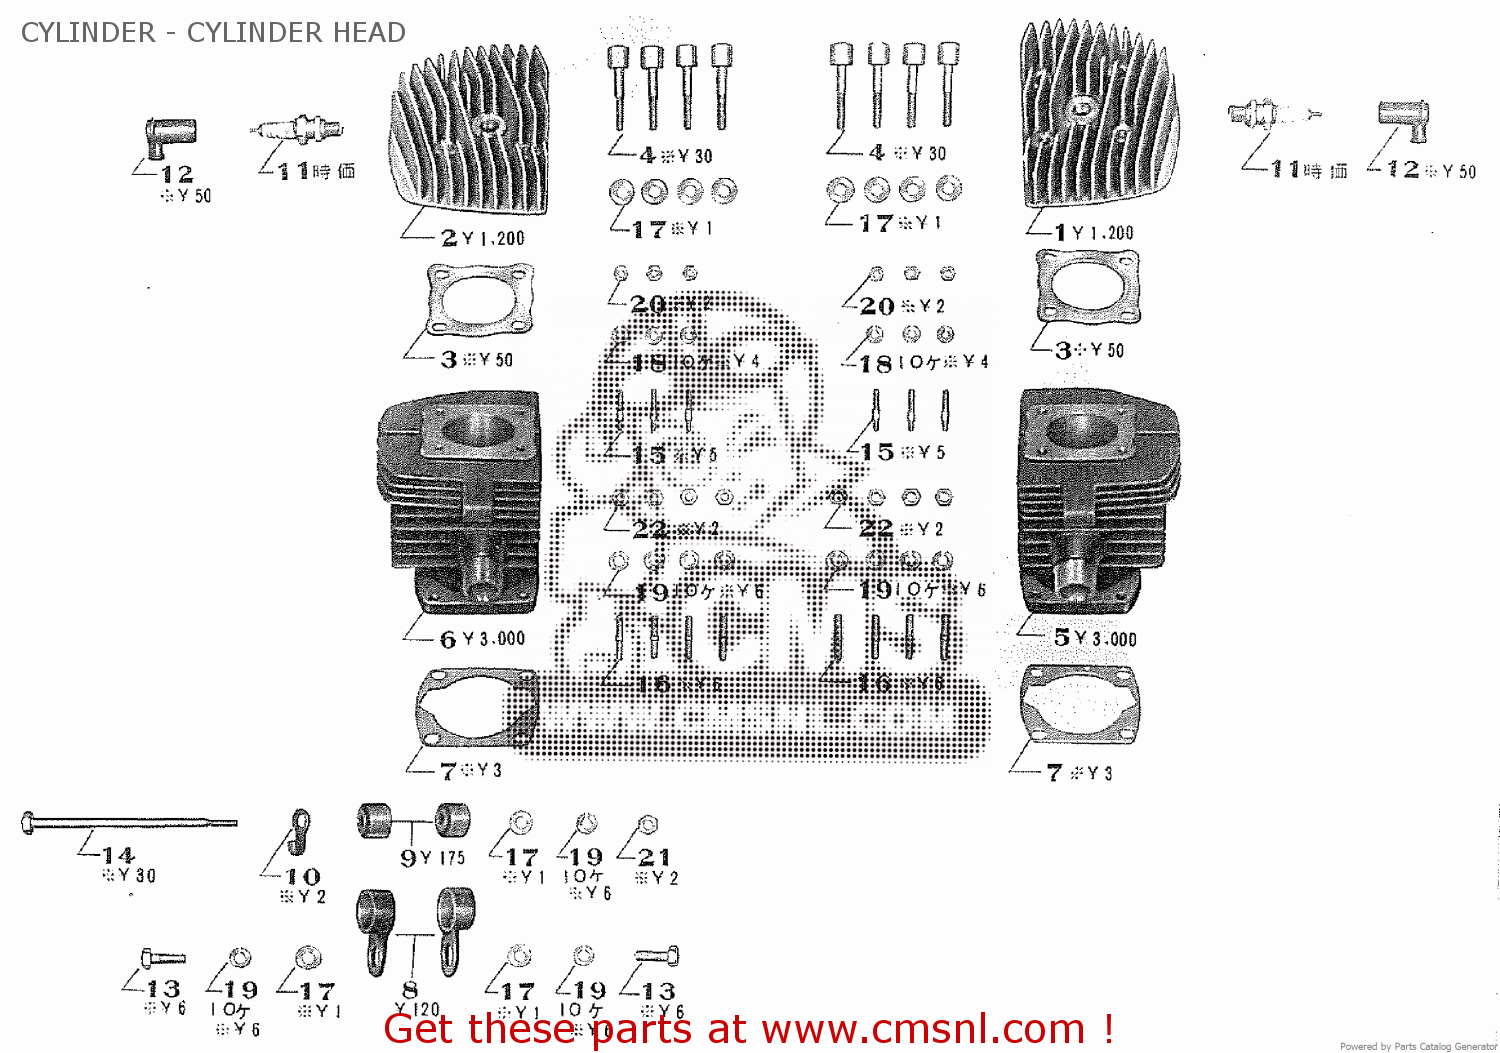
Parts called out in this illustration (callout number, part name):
1	RIGHT CYLINDER HEAD
2	LEFT CYLINDER HEAD
3	CYLINDER HEAD GASKET
4	CYLINDER HEAD SET BOLT
5	RIGHT CYLINDER
6	LEFT CYLINDER
7	CYLINDER PACKING
8	CYLINDER SUPPORTER COMP.
9	ENGINE SUPPORTER BUSH
10	CLUTCH WIRE CLIP
11	PLUG COMP. (B-7)
12	PLUG CAP
13	8X25 HEXAGON BOLT
14	8X150 HEXAGON BOLT
15	6X22 STUD BOLT
16	8X16 STUD BOLT
17	8MM PLANE WASHER
18	6MM SPRING WASHER
19	8MM SPRING WASHER
20	6MM HEXAGON NUT
21	8MM HEXAGON NUT
22	8MM LIGHT HEXAGON NUT
